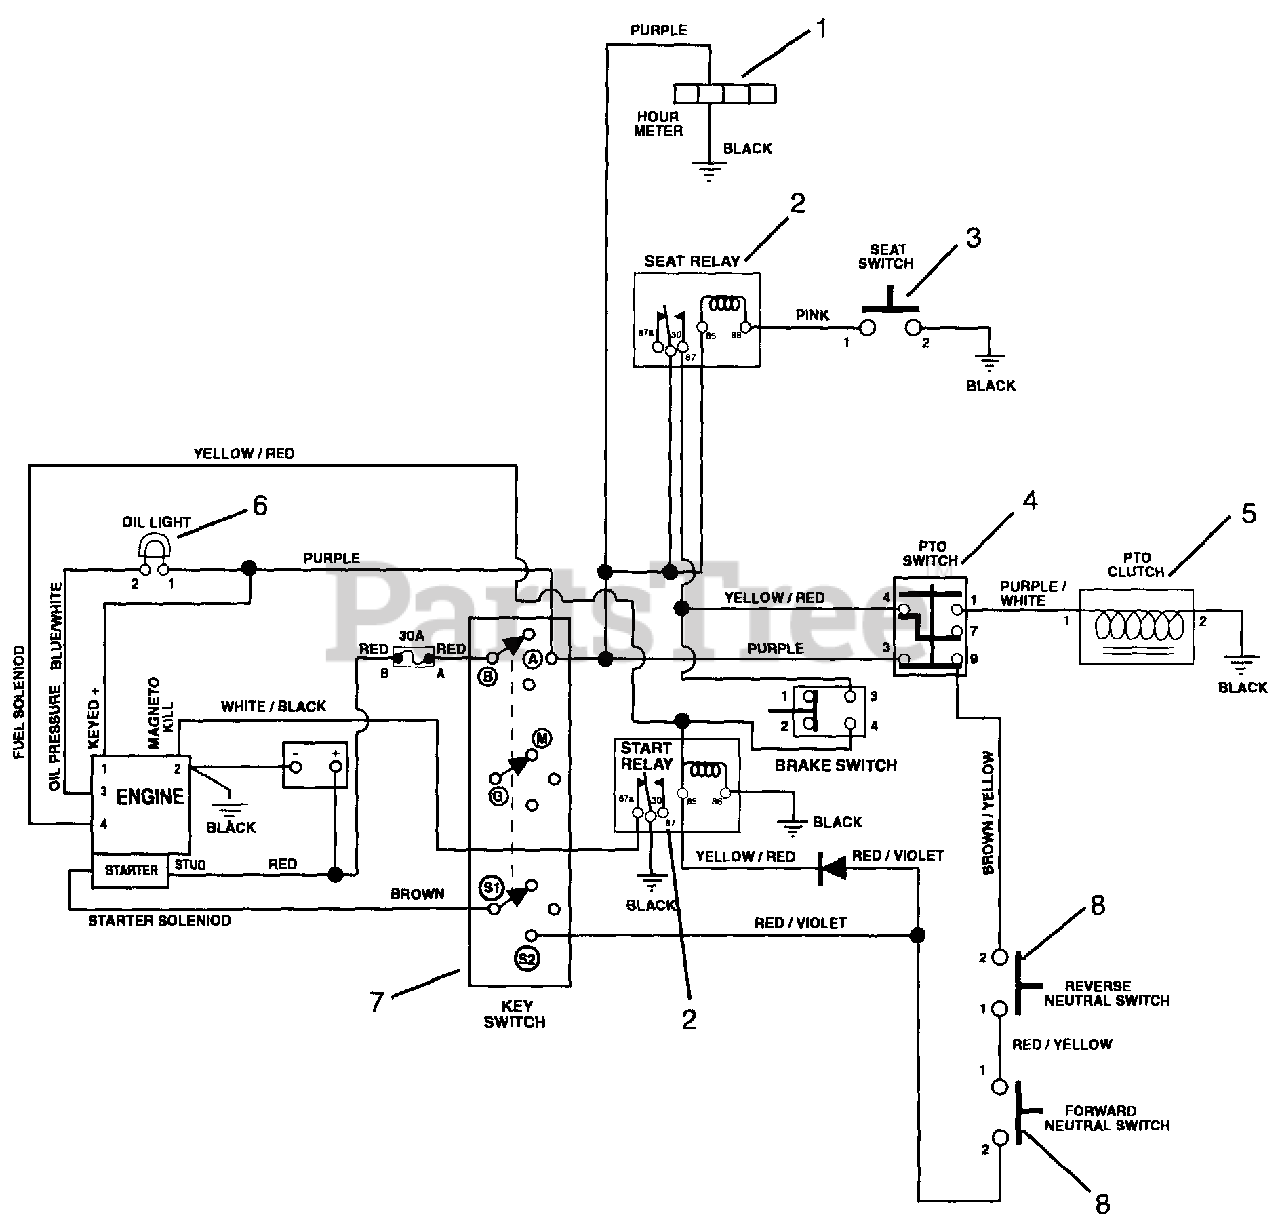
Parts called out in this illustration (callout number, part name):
1	Hour Meter
2	Relay
3	Seat Switch
4	Switch, Clutch with Retainer Ring
5	Clutch, Electric
6	Light, Indicator
7	Key Switch
